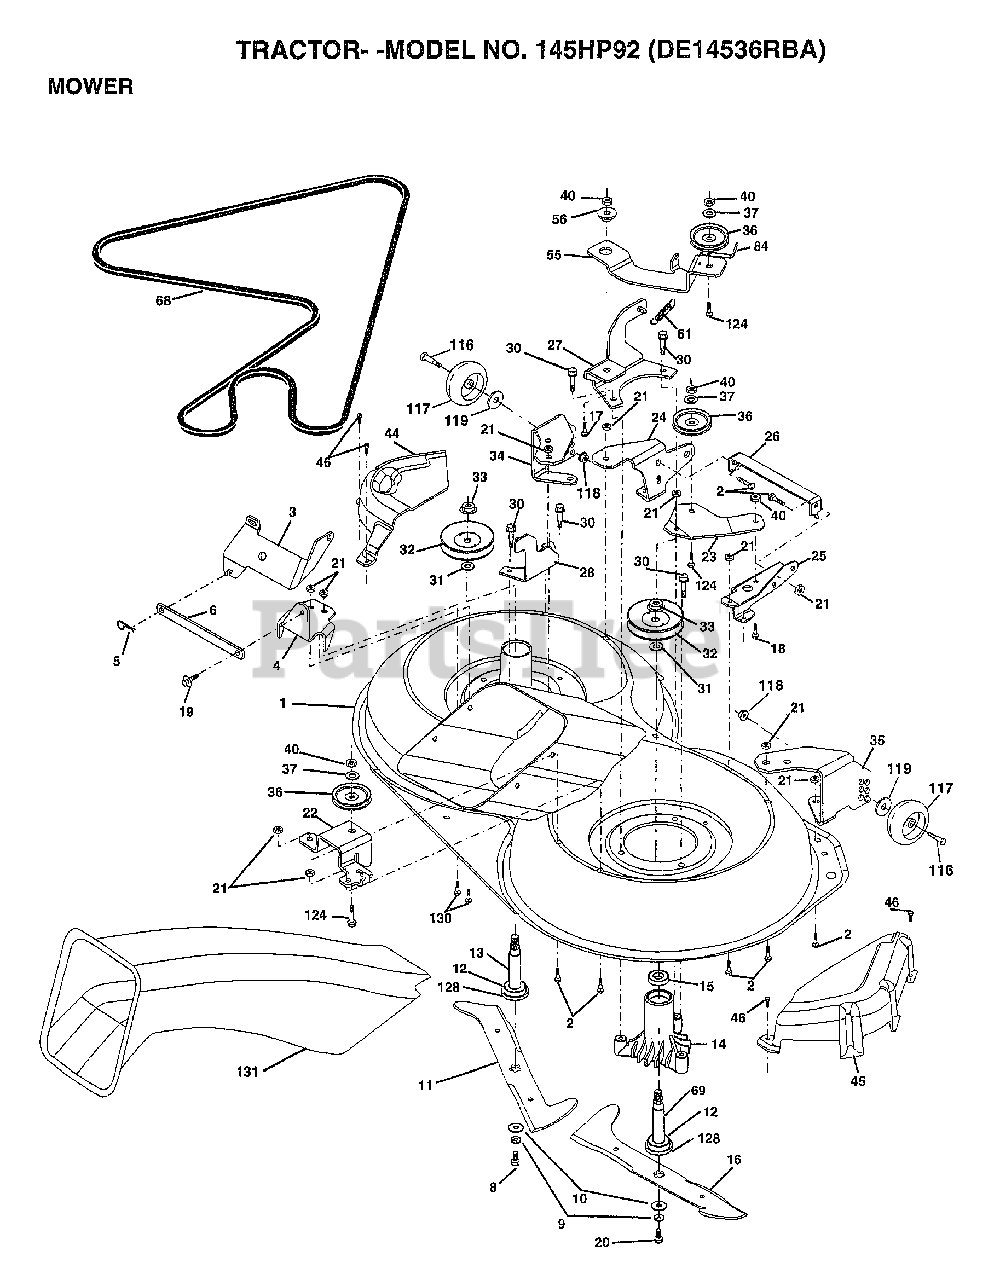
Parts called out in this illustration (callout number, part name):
1	HOUSING.ASM.MOWER
2	BOLT
3	BRKT.ASM.S-BAR.CHASSIS
4	BRKT.BAR.SWAY.DECK
6	BAR.SWAY.92.CRD
8	BLADE BOLT
10	WASHER.HARD.BLADE
11	BLADE.3-1.LH.92.CRD
12	BEARING.BALL
14	HSG ASM MANDREL
15	BEARING
16	BLADE.3-1.RH.CRD.92
17	BOLT.3/8-14X1.25
18	BOLT D
19	BOLT SHD 5/16-18
20	BOLT.3/8-24X1.25
22	BRKT.IDLER.SPRT.CRD
23	"BRKT.IDLER.SPRT.RF.92,CRD"
24	BRKT.SUSP.LF.92.CRD
25	BRKT.SUSP.RF.92.CRD
26	BRACE.SUPT.SUSP.FRT.CRD
27	BRKT.ASM.SUSP.RR.92.CRD
28	BRKT.ASM.SUSP.LR.92.CRD
30	"SCREW-THD ROLL,WA"
31	WASHER
32	PULLEY.MAND.36/46
34	BRKT.GUAGE.WHL.LF.92.CRD
35	BRKT.GUAGE.WHL.RF.92.CRD
36	PULLEY.IDLER.4.25
37	WASHER
44	COVER.MANDREL.LH.92.CRD
45	COVER.MANDREL.RH.92.CRD
46	SCREW.1/4-20X5/8
55	ARM.IDLER.92.CRD
56	SPACER RETAINER
61	SPRING.TENSION.BELT
68	HEX-BELT.92.MWR.105AA
69	SHAFT.ASM.W/LWR.BRG.RH.THD
84	"KEEPER-BELT,IDLER"
116	BOLT.SHOULDER
117	WHEEL GAGE DONUT
118	LOCKNUT
119	WASHER
124	BOLT.3/8-16X1.50
128	WASHER.FELT.
131	CHUTE.BAGGER.CRD
